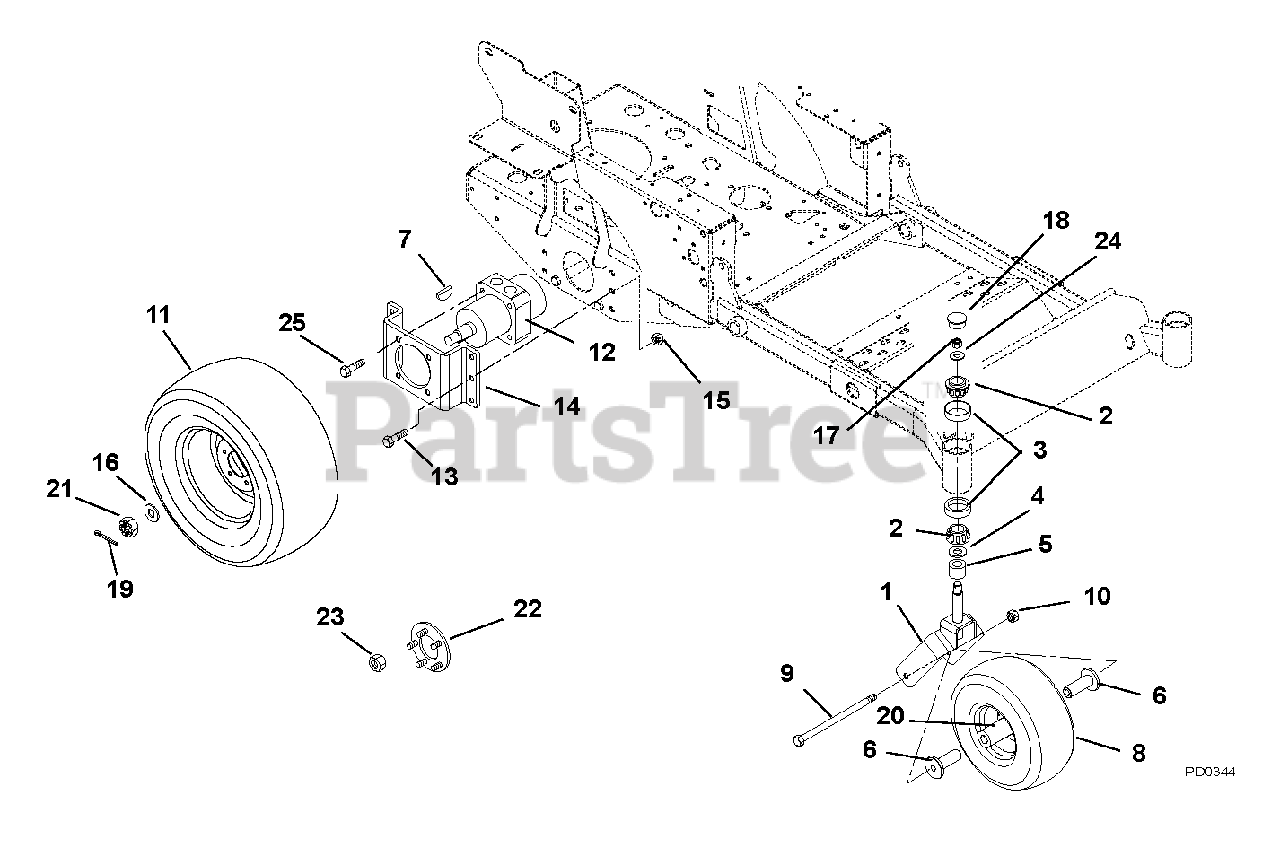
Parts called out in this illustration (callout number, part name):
1	Weldment, Front Fork
2	Bearing, Cone with Grease, 1.0 x .58
3	Bearing, Cup 1.980 x .420
4	Bearing Seal 1.5 x 2 x .18
5	Spacer, PM, 1.03 I.D. x 1.5 O.D. x .375
6	Spacer, Wheel
7	Key, Woodruff .31 x 1.00 (Included with Item 12)
8	Tire/Wheel Assembly, 13 x 5.00-6
9	Bolt, Hex .50-13 x 7.50 Grade 5
10	Nut, Nyloc Flange .50-13
11	Tire/Wheel Assembly, 21 x 7.00-10
12	Motor, Hydraulic Wheel (20)
13	Bolt, Hex .38-16 x 1.00 Grade 5
14	Bracket, Wheel Motor
15	Nut, Nyloc Flange 3/8-16
16	Washer, Flat Steel .755 x 1.375 x .062
17	Nut, Center Lock Jam .75-16
18	Cap, Dust
19	Pin, Cotter .09 x 1.25 Extended Prong Square Cut
20	Bearing, 25mm I.D. x 52mm OD x 15mm (Included with item 8)
21	Nut, Hex .75-20
22	Assembly, Service Hub with Studs
23	Wheel Nut .437-20
24	Washer, Flat, Steel .812 x 1.250 x .062
25	Bolt, Hex .38-16 x 1.00 Grade 8 Epoxy 30
